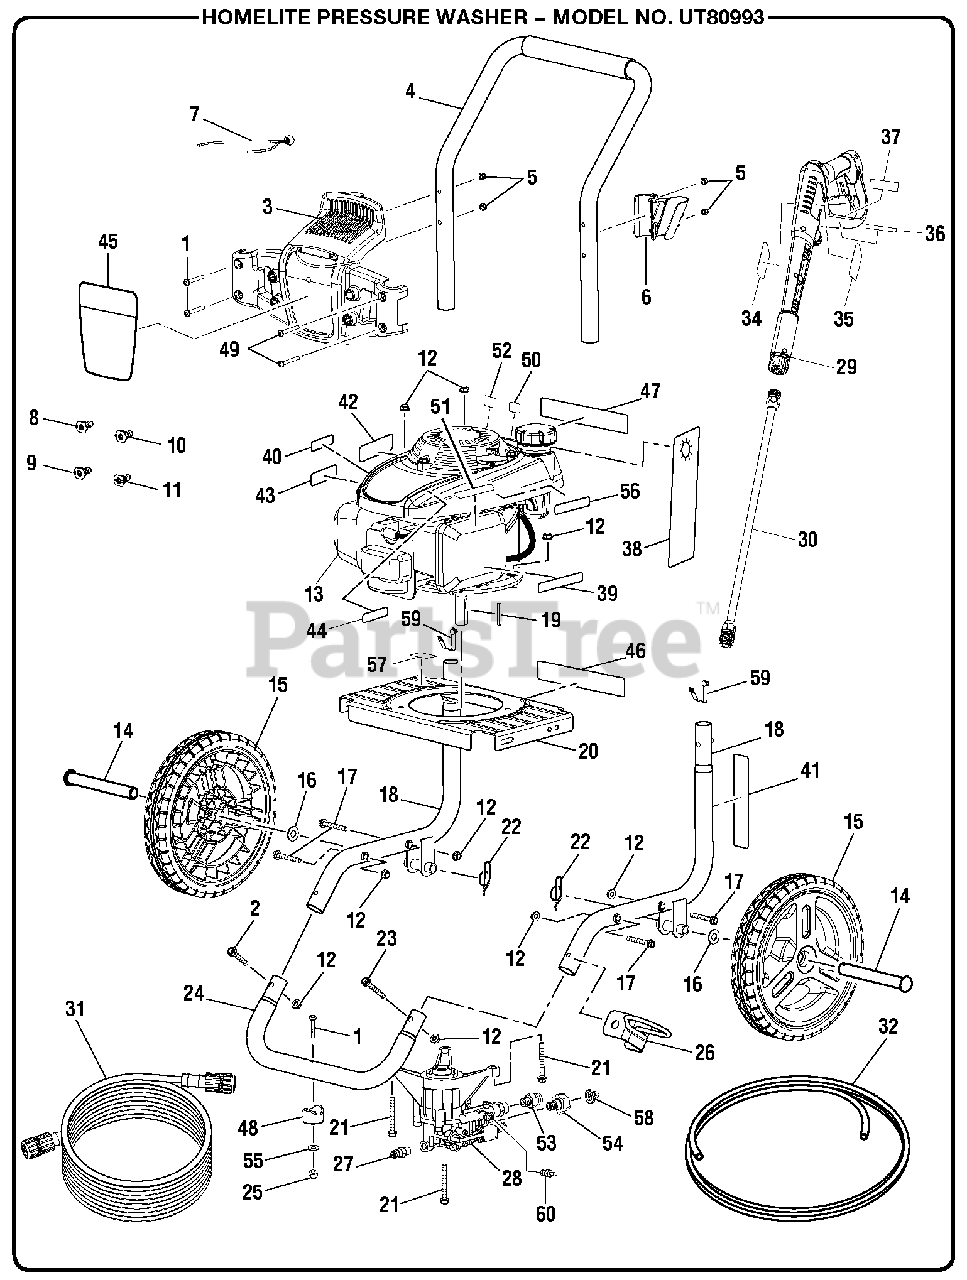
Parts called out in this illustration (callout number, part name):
1	Screw (1/4-20 x 1.85 in., T30 Torx Hd.)
2	Bolt (M8 x 45 mm)
3	Hose and Nozzle Holder Assembly
4	Handle w/Foam
5	Lock Nut (1/4-20)
6	Wand Holder
7	Bungee Cord Assembly
8	40deg Nozzle
9	Soap Nozzle
10	25deg Nozzle
11	0deg Nozzle
12	Flange Nut (M8 x 1.25)
13	Engine
16	Washer (1/2 in.)
17	Bolt (M8 x 55 mm, Flange Hd.)
18	Main Frame Assembly
19	Output Shaft Key (40 mm)
20	Engine Plate
21	Bolt (M8 x 60 mm, Flange Hd.)
22	Axle Clip
23	Bolt (M8 x 50 mm)
24	Front Frame
25	Lock Nut (1/4-20)
26	Wand Holder Loop
27	Thermal Release Valve
28	Pump
29	Trigger Handle Assembly
30	Extension Wand
31	Hose (25 ft., 3000 psi)
32	Chemical Siphon Tube
33	Chemical Siphon Filter
34	Label (Wand Logo)
35	Label (Wand Warning)
36	Fr/Sp Label (Wand Warning)
37	Label (Wand Rating)
38	Danger Hangtag
39	Engine Quick Start Label
40	Combustion Label
41	Pump Quick Start Label
42	Danger Label
43	Hot Surface Label
44	EMC Label
45	Performance Label
46	Data Label
47	Danger Label
49	Screw (1/4-20 x 2 in., T30 Torx Hd.)
50	No E85 Label
51	Inquiries Label
52	Lubricant Label
53	Outlet Tube
54	Inlet Tube
55	Washer (1/4 in.)
56	Release Water Label
57	Oil Fill Location Label
58	Filter Screen (Pump Inlet)
59	Lock Button w/Spring Clip
60	Detergent Suction Kit
